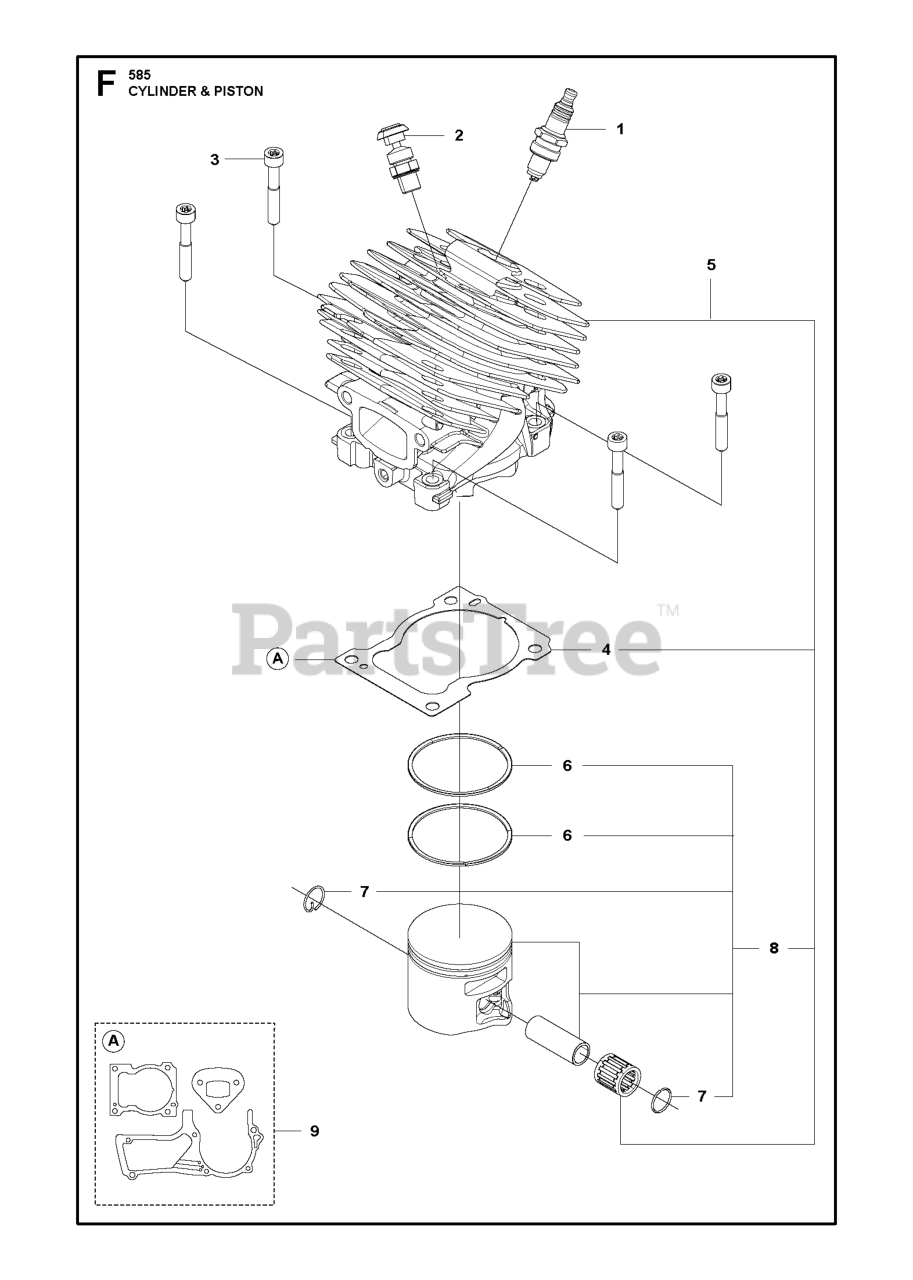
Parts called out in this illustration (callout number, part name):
1	CMR6H SPARK PLUG NGK
2	DECOMPRESSION VALVE
3	SCREW ISO 14579 M 6 X 40 12.9
4	GASKET CYLINDER 0
5	CYLINDER KIT D53 H585 SPARE PA
6	PISTON RING R-53X1.2-MC53
9	GASKET KIT 90 CC SPARE PART
